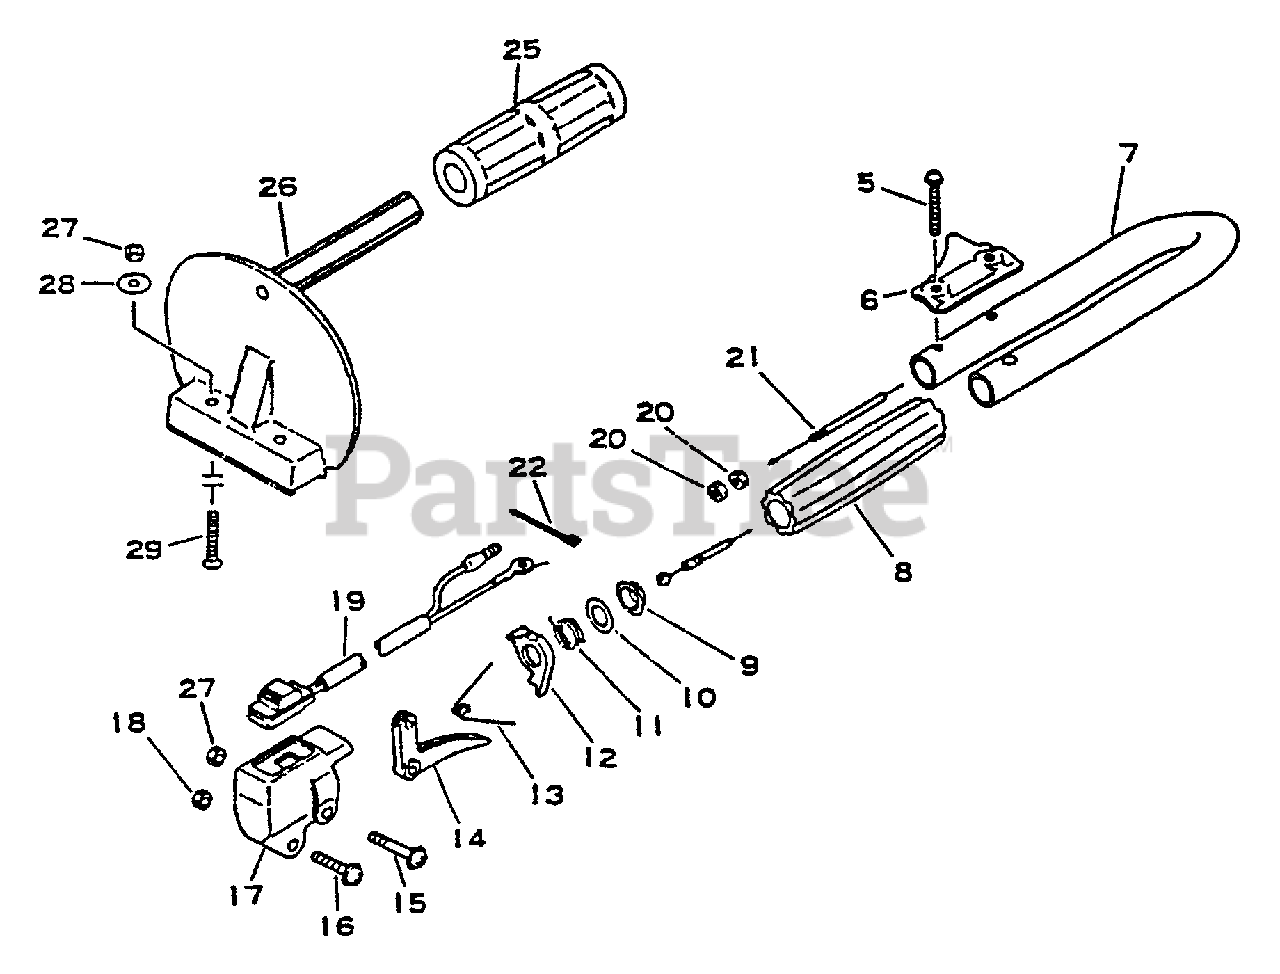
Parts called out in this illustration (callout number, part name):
5	SCREW - 5X35
6	BRACKET, HANDLE
7	HANDLE - REAR
8	GRIP, HANDLE
10	SPACER
11	SPRING, LOCKOUT LEVER
12	LOCKOUT, THROTTLE
13	SPRING, TRIGGER
14	TRIGGER, THROTTLE
15	SCREW - 5X30
16	SCREW - 5X28
17	BRACKET, THROTTLE
19	IGNITION SWITCH ASSY
21	CABLE, THROTTLE
25	GRIP, HANDLE
26	HANDLE - FRONT
27	LOCKNUT - 5
29	SCREW - 5X30
